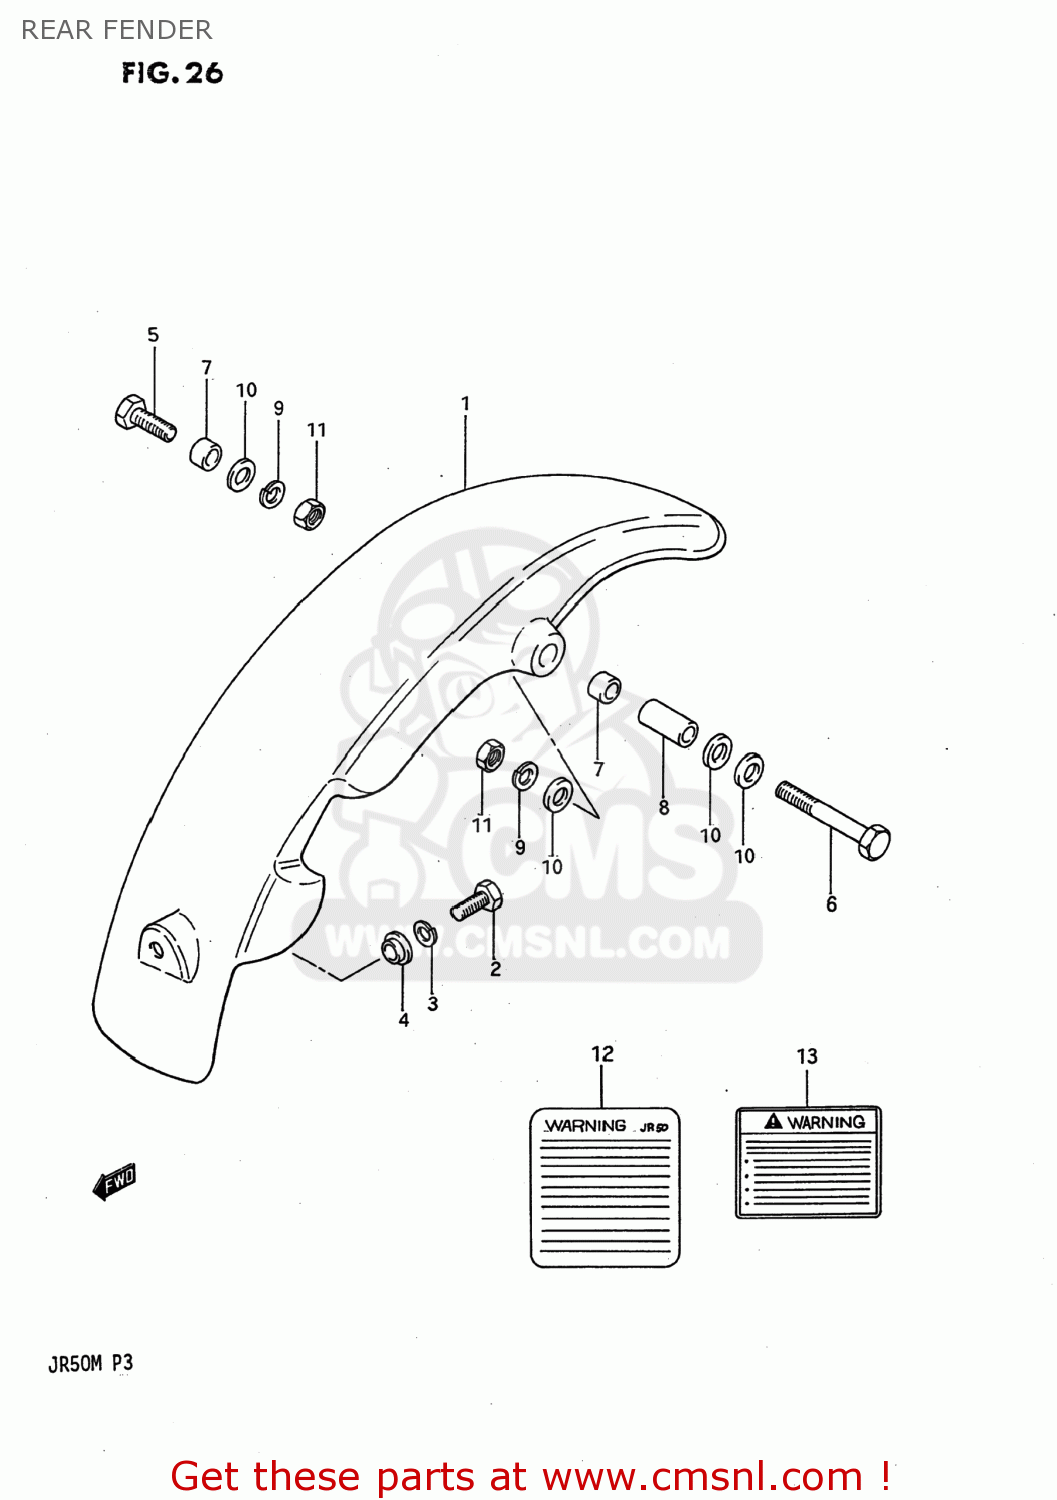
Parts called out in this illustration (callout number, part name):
1	FENDER,RR
2	BOLT
3	WASHER,LOCK
4	WASHER
5	BOLT
6	BOLT 8X50
7	SPACER,RR FENDER RR
8	SPACER (8.2X12.5X23.5)
9	LOCK WASHER
10	WASHER
11	NUT
12	LABEL (WARNING)
13	LABEL
